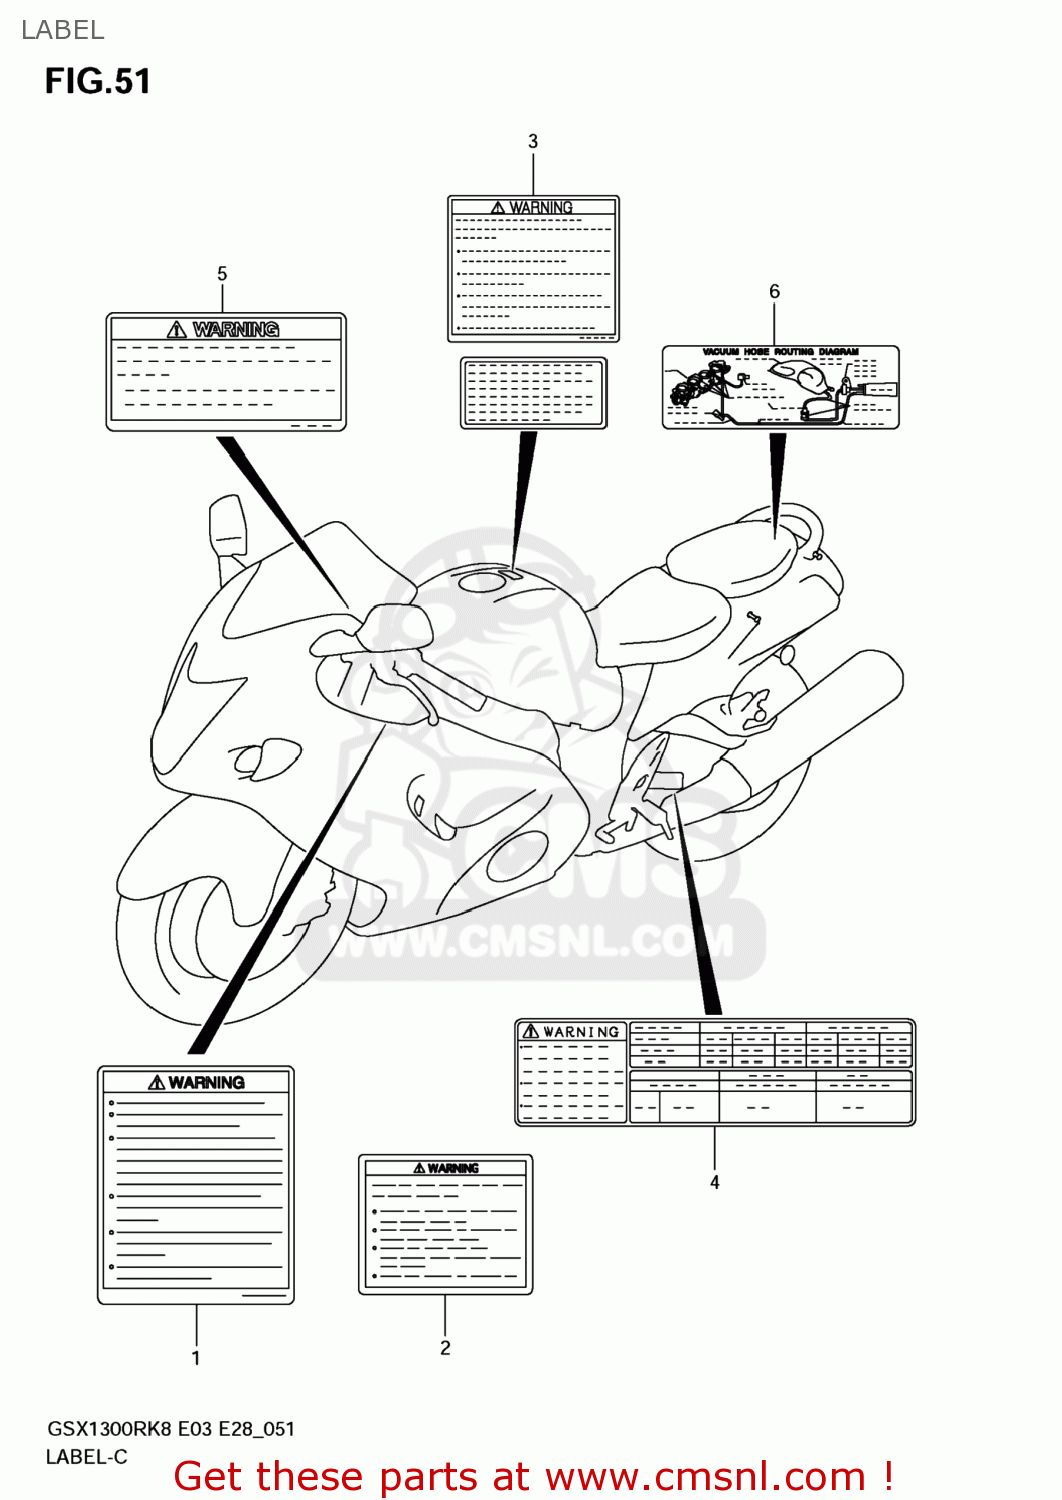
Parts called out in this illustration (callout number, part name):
1	LABEL,GENERAL WARNING
2	LABEL,SCREEN
3	LABEL,MANUAL NOTICE
4	LABEL,TIRE INFORMATION
5	LABEL,WARNING STEERING
6	LABEL,VACUUM HOSE ROUTING
7	MANUAL,OWNER'S
